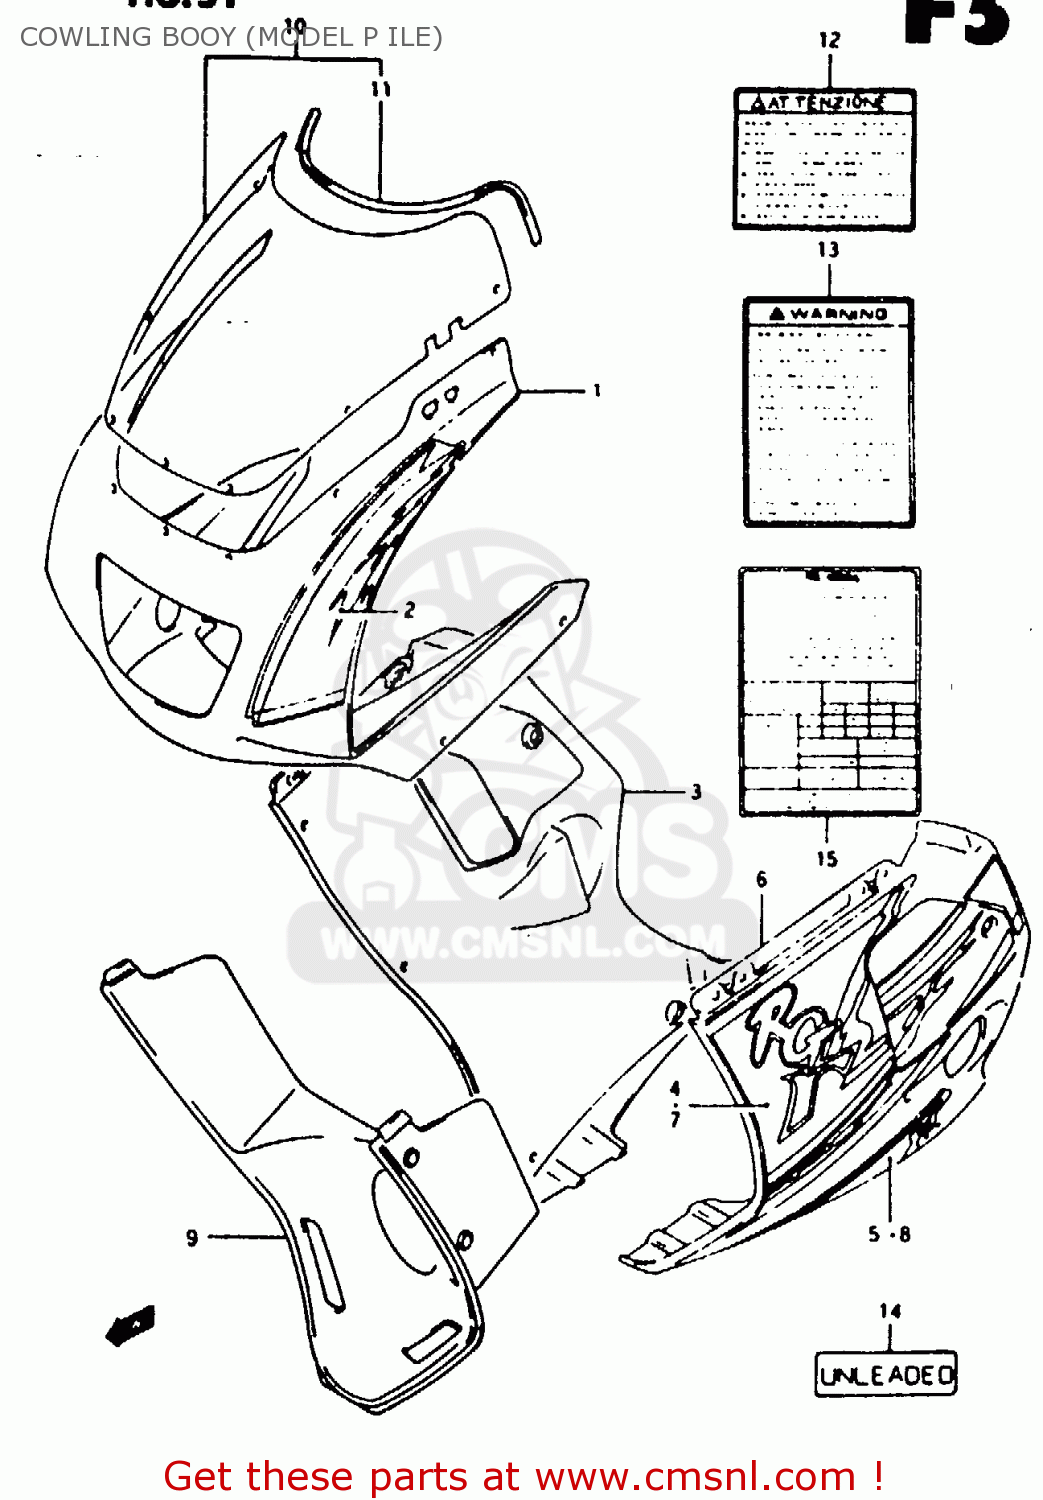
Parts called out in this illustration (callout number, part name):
1	COWLING ASSY, BODY (BLUE)
2	TAPE SET, COWLING
3	COWLING ASSY, UNDER RH (BLUE)
4	TAPE SET, UNDER RH
5	TAPE,COWL UNDER,R
6	COWLING ASSY, UNDER LH (BLUE)
7	TARE SET, UNDER LH
8	TAPE,COWL UNDER,L
9	COWLING, UNDER CENTER (BLACK)
10	SCREEN SET, WIND
11	MOLDING
12	LABEL, WARNING SAFETY
13	LABEL (WARNING SCREEN)
14	LABEL,CAUTION
15	LABEL, TIRE AIR PRESSURE
16	MANUAL, OWNER'S
